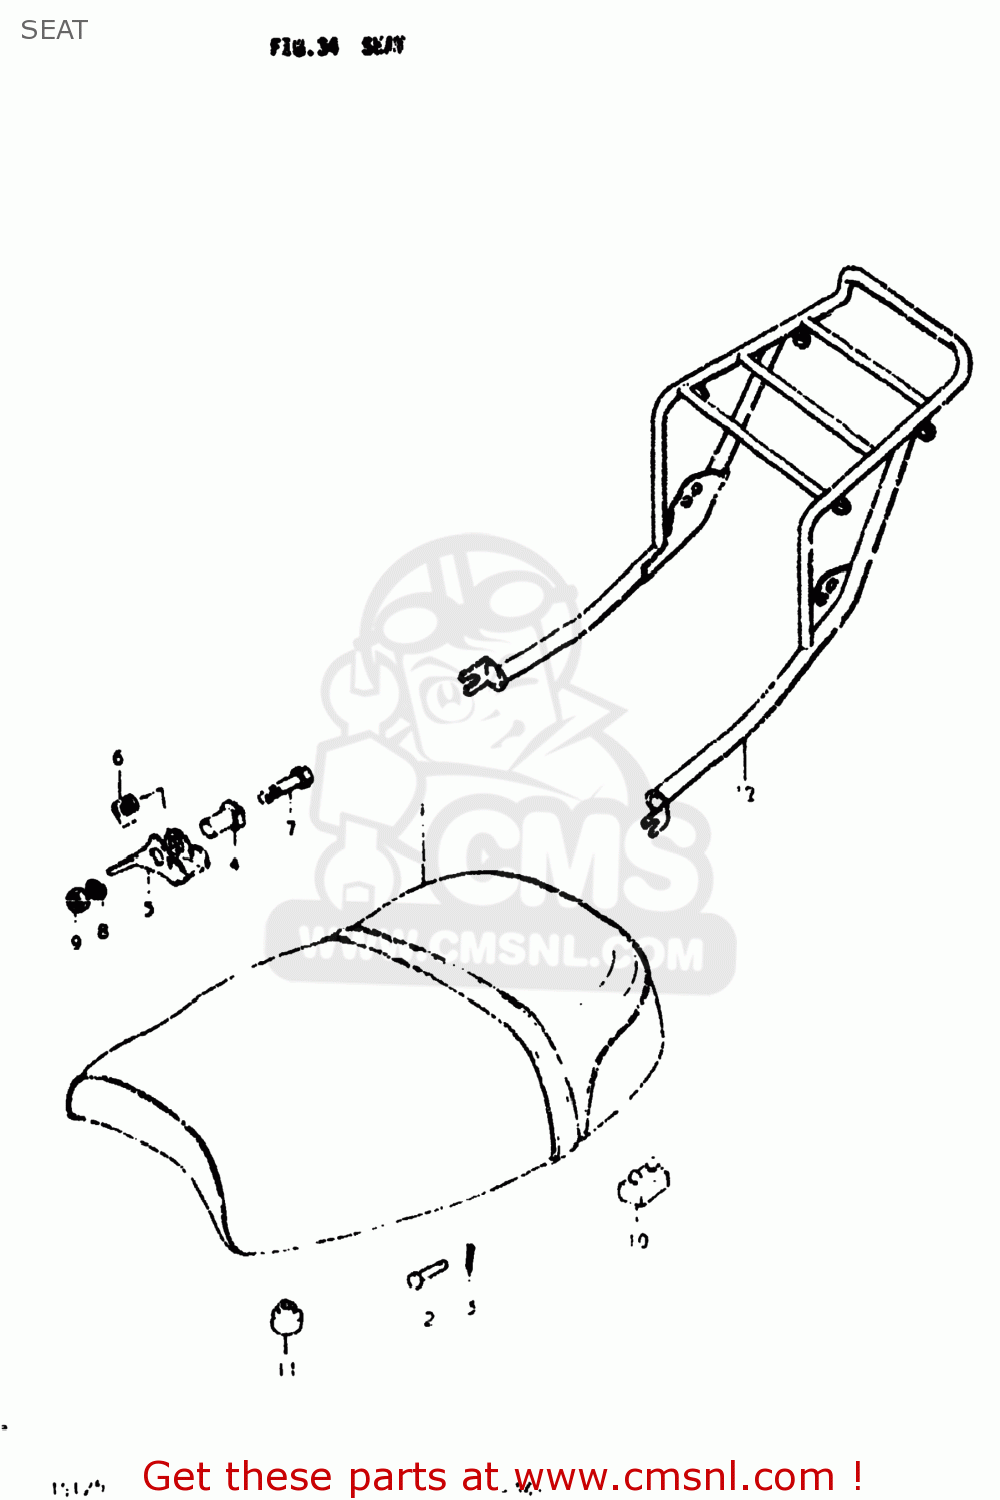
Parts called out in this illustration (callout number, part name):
1	SEAT ASSEMBLY
2	PIN
3	PIN
4	STRIKER,SEAT LOCK
5	STRIKER,SEAT LOCK
6	SPRING
7	BOLT 8X45
8	LOCK WASHER
9	NUT
10	CUSHION
11	CUSHION(11.5X22X20)
12	CARRIER
